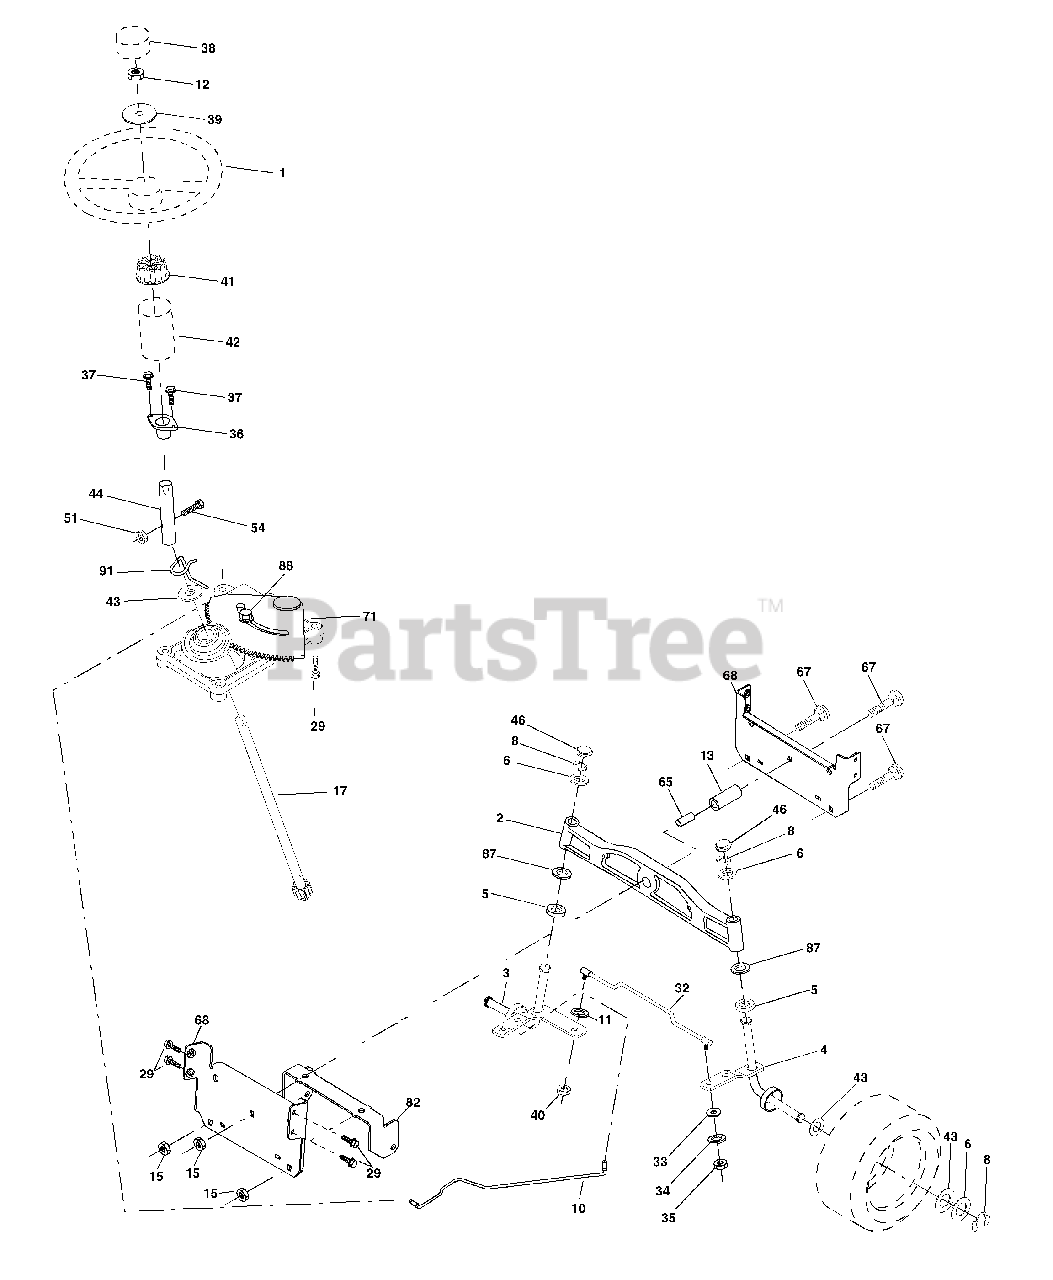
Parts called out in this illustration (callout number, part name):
1	Wheel Steering
2	Axle Cast LT Machined
3	Spindle Asm Cast LH
4	Spindle Asm Cast RH
5	Bearing Race Thrust Harden
6	Washer 25/32 X 1-5/8 X 16 Ga
8	Ring Klip #t5304-75
11	Washer Lock Hvy Hlcl Spr 3/8
12	Nut Hex Jam Toplock 1/2-20
13	Spacer Brg Axle Front
15	Nut Hex Flange Lock Yel D
17	Shaft Asm Steering
29	Screw 3/8-16x3/4
33	Washer 11/32 x 3/4 x 16 Ga.
34	Washer Lock Hvy. Helical 5/16 SD
35	Nut Crown Lock 5/16-24
36	Bushing Strg
37	Screw TT #32.5 x 5 x 3/8 Flange
38	Cap Wheel Steer
39	Washer 9/16 x 2-3/8
40	Nut Lock Center 3/8-24 Unf
41	Adaptor Wheel Strg
42	Boot Dash Steering
43	Washer 25/32 X 1 1/4 X 16 Ga
44	Extension Steering
46	Cap Spindle Fr Top Blk
51	Nut 1/4-28
54	Bolt Hex 1/4-28 x 1-1/4
63	Bolt Fin Hex 3/8-16 UNC x 1 Gr. 5
65	Spacer, Brace Axle
67	Bolt Rdhd 3/8-16 x 2-1/4
68	Brace, Axle
71	Steering Asm.
82	Bracket Susp Chassis Front 15"
87	Washer Flat .781 x 1-1/2 x .14
88	Bolt Shoulder 7/16-20
91	Clip, Steering
